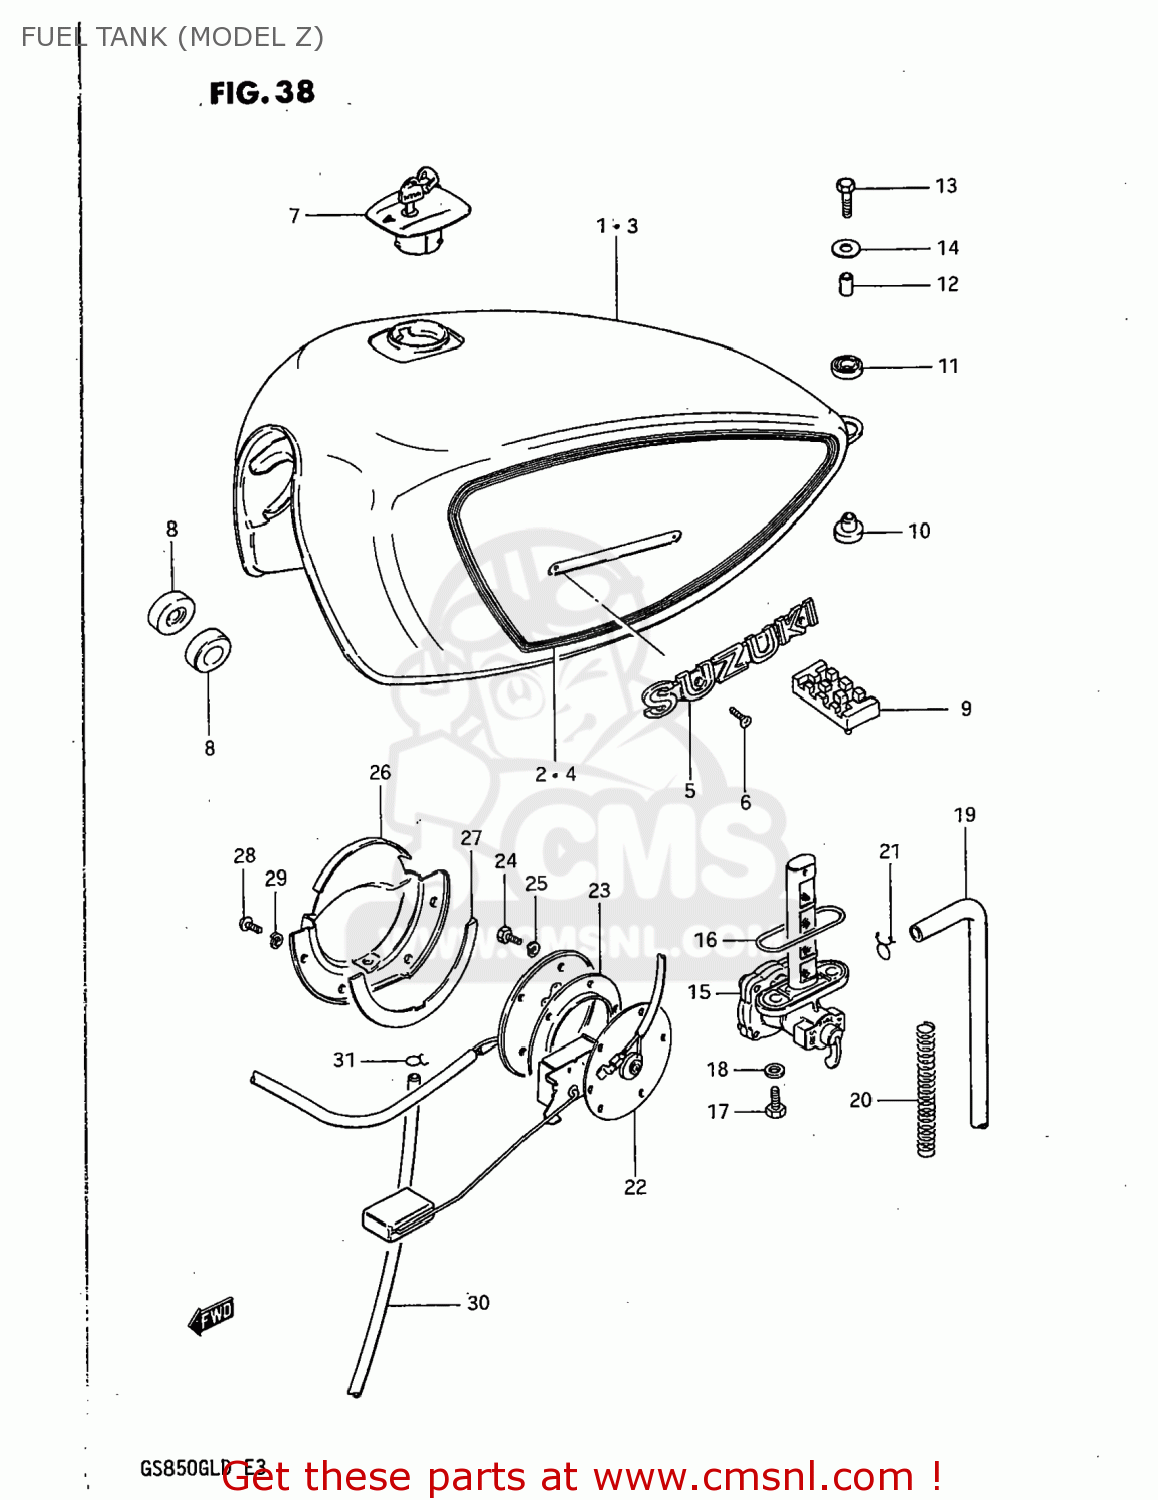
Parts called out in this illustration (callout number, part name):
1	TANK ASSEMBLY,FUEL
2	TAPE SET,FUEL TANK
3	TANK ASSEMBLY,FUEL
4	TAPE SET,FUEL TANK
5	EMBLEM,FUEL TANK
6	SCREW 3X6
7	CAP SET,FUEL TANK
8	CUSHION
9	CUSHION,FUEL TANK CTR
10	CUSHION
11	CUSHION
12	SPACER
13	BOLT
14	WASHER (6.5X24X1.6)
15	COCK ASSEMBLY,FUEL
16	O RING
17	BOLT(6X20)
18	GASKET
19	HOSE
20	SPRING
21	CLIP
22	GAUGE ASSEMBLY,FUEL LEVEL
23	GASKET,FUEL LEVEL GAUGE (NAS)
24	BOLT
25	LOCK WASHER
26	PLATE,FUEL DRAIN
27	GASKET (NAS)
28	SCREW
29	LOCK WASHER
30	HOSE
31	CLIP
